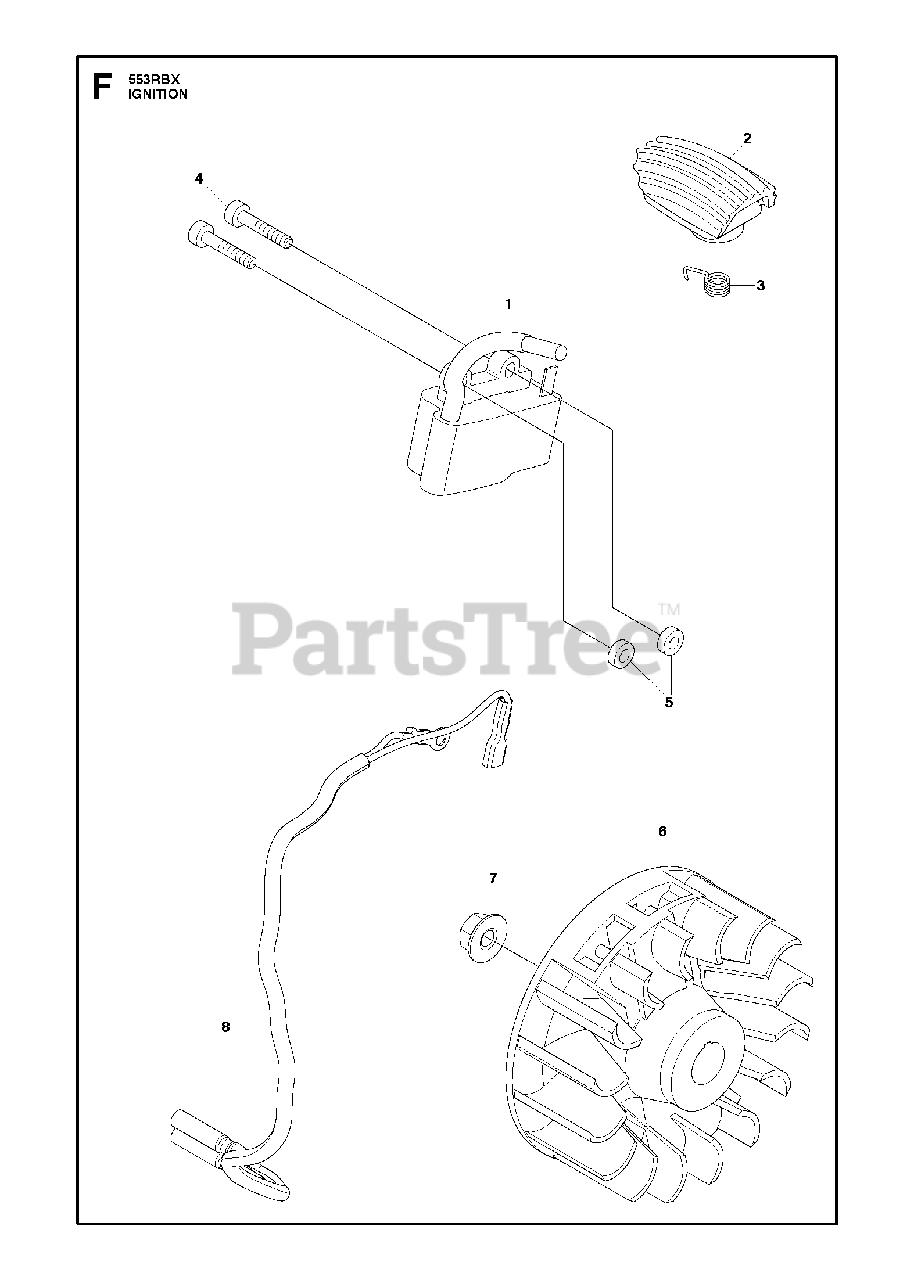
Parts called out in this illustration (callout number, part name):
5	SPACER
7	RP_NUT, M10
8	CORD-COMP
